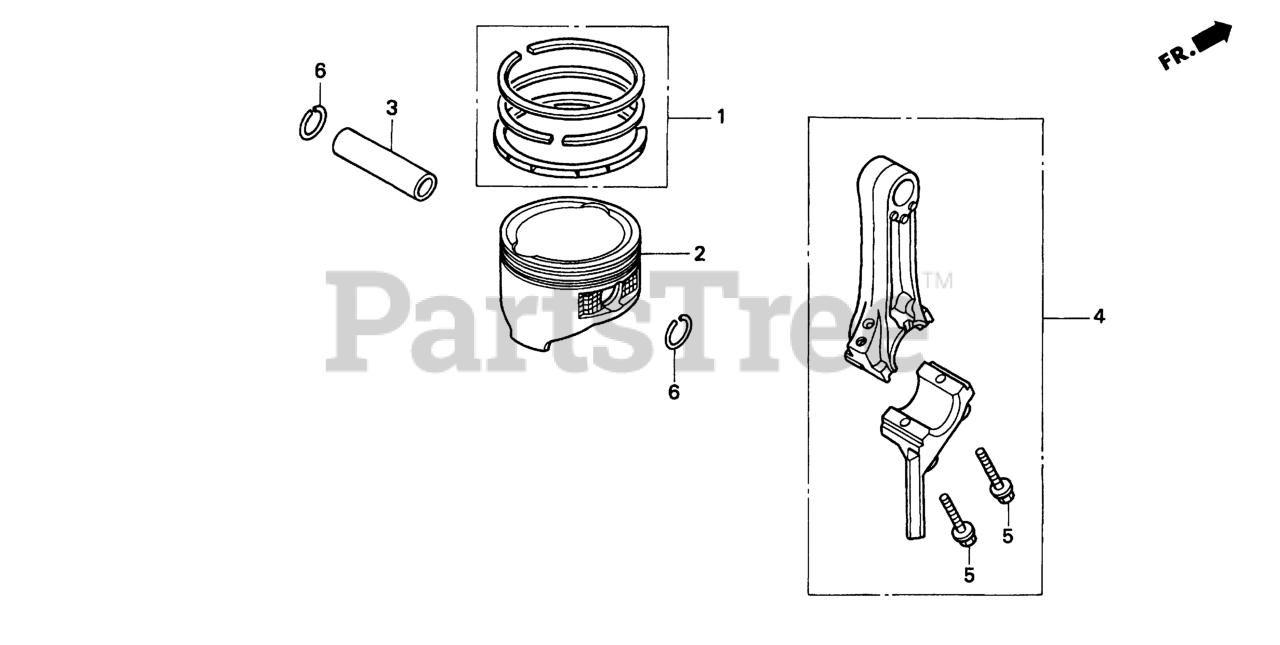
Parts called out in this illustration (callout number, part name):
1	RING SET, PISTON (RIKEN)
3	PIN, PISTON
4	ROD ASSY., CONNECTING
5	BOLT, CONNECTING ROD
6	CLIP, PISTON PIN (13MM)
